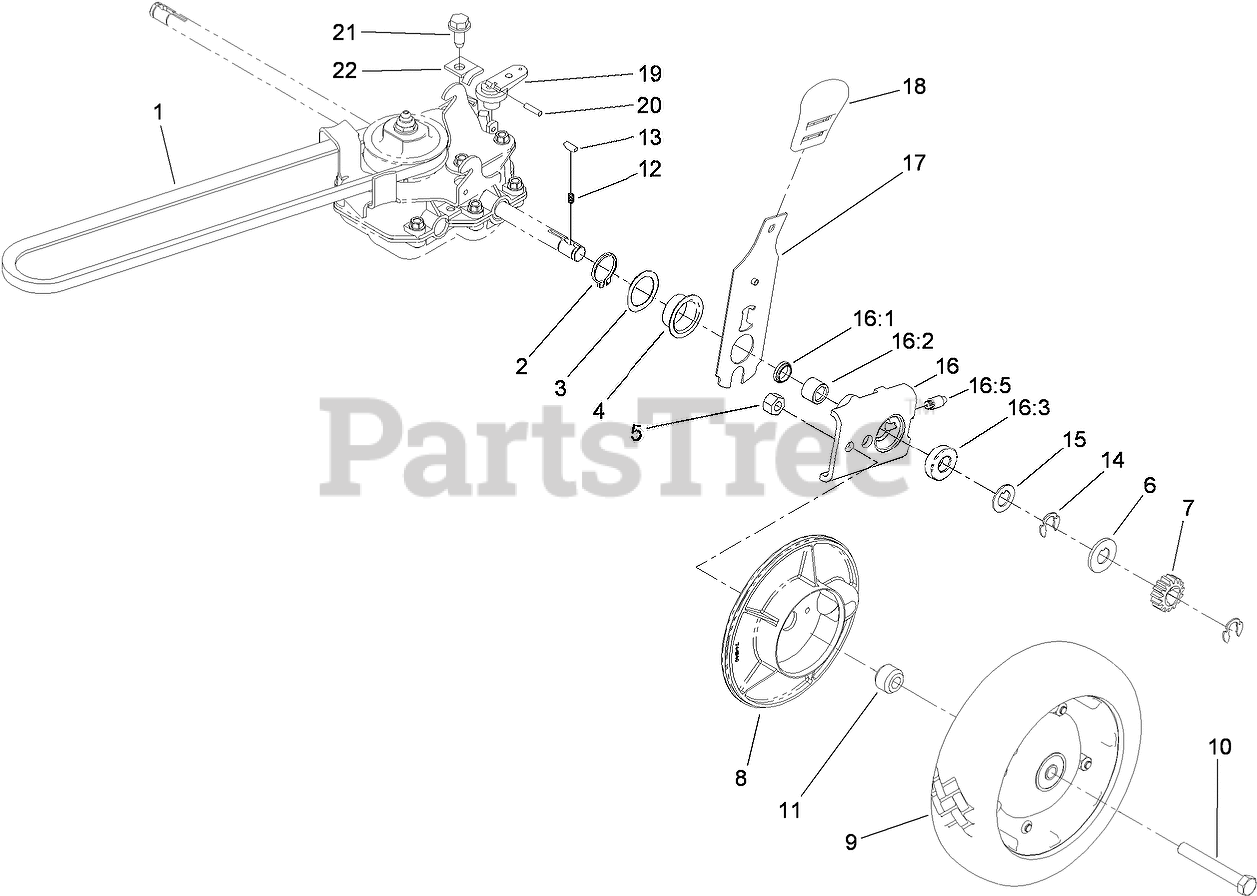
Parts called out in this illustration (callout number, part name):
1	V-BELT
2	RING-RETAINING
3	WASHER
4	CAP-END
5	NUT-LOCK, CONE
6	WASHER-THRUST, OUTER
7	GEAR-PINION
8	COVER-WHEEL
9	Wheel And Tire ASM
10	SCREW-HH
11	SPACER-COVER, WHEEL
12	SPRING-COMPRESSION
14	RING-RETAINING
15	WASHER-THRUST, OUTER
16	PIVOT ARM ASM
16:1	SEAL-OIL
16:2	BEARING-CAGED NEEDLE ROLLER
16:3	BEARING-WHEEL
17	REAR SPRING ARM ASM
18	KNOB-HOC
19	LEVER-SHIFT
20	PIN-COIL
21	SCREW-HWHTF
22	CLAMP-CABLE
